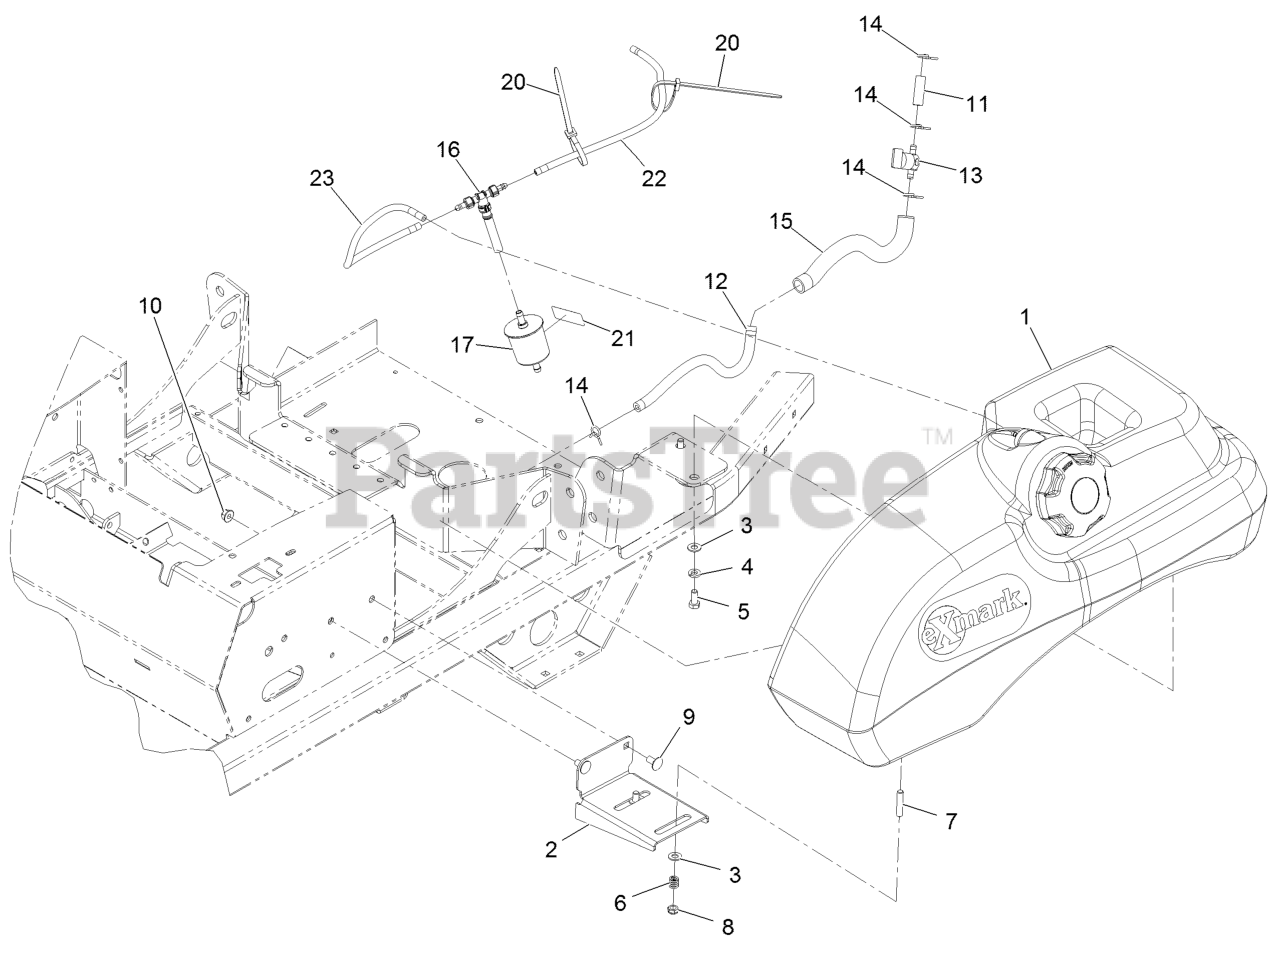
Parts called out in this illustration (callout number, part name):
1	ASM-FUEL TANK
2	BRACKET-TANK AND FENDER
3	WASHER-PLAIN
4	WASHER-LOCK
5	SCREW-HH
6	SPRING-TANK, FUEL
7	STUD
8	NUT-LOCK, NI
9	SCREW-CARR
10	NUT-HF, NI
11	HOSE-FUEL
12	HOSE-FUEL
13	VALVE-FUEL
15	CONDUIT-FUEL LINE
16	TEE AND CHECK
17	FILTER-FUEL
20	TIE-PLASTIC
21	DECAL-FILTER, EMISSIONS
22	HOSE,EMISSIONS
23	HOSE-EMISSIONS
